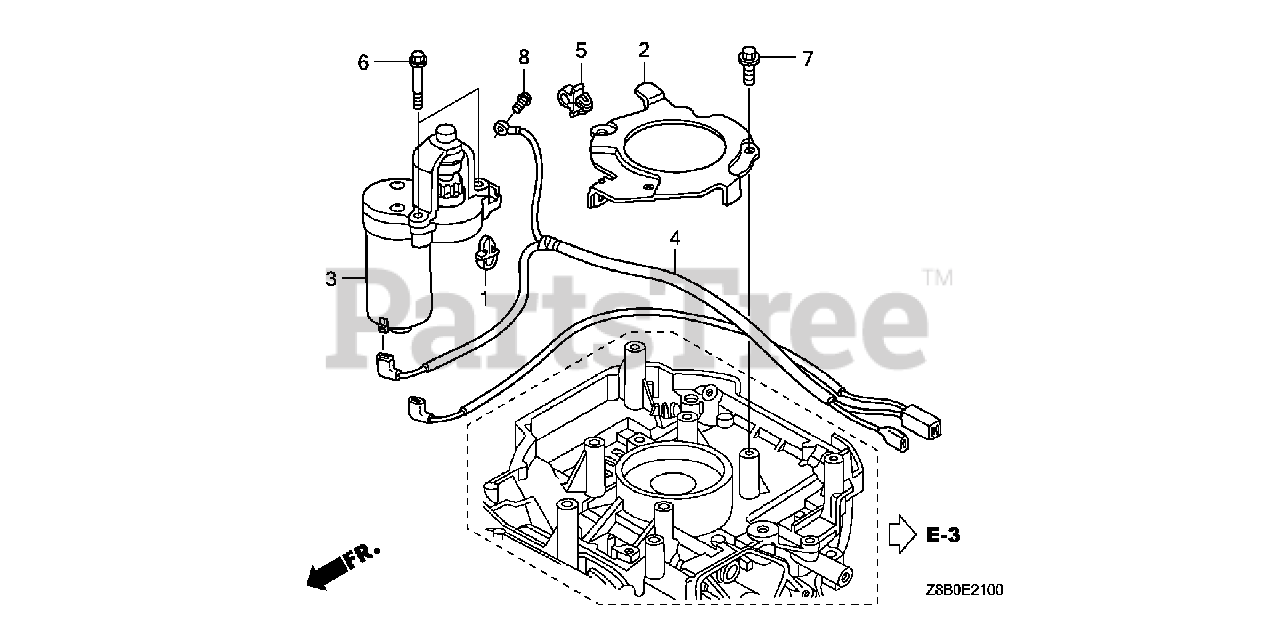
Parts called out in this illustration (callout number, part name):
1	HOLDER, WIRE
2	CLAMP, WIRE
3	STARTER MOTOR ASSY.
4	WIRE, TERMINAL GROUND
5	HOLDER, WIRE (FASTEX)
5	CLIP A, CABLE (3.8MM BLACK) (NIFCO)
6	BOLT, SPECIAL (6MM)
7	BOLT, FLANGE (6X12) (CT200)
8	SCREW, PAN (5X8)
